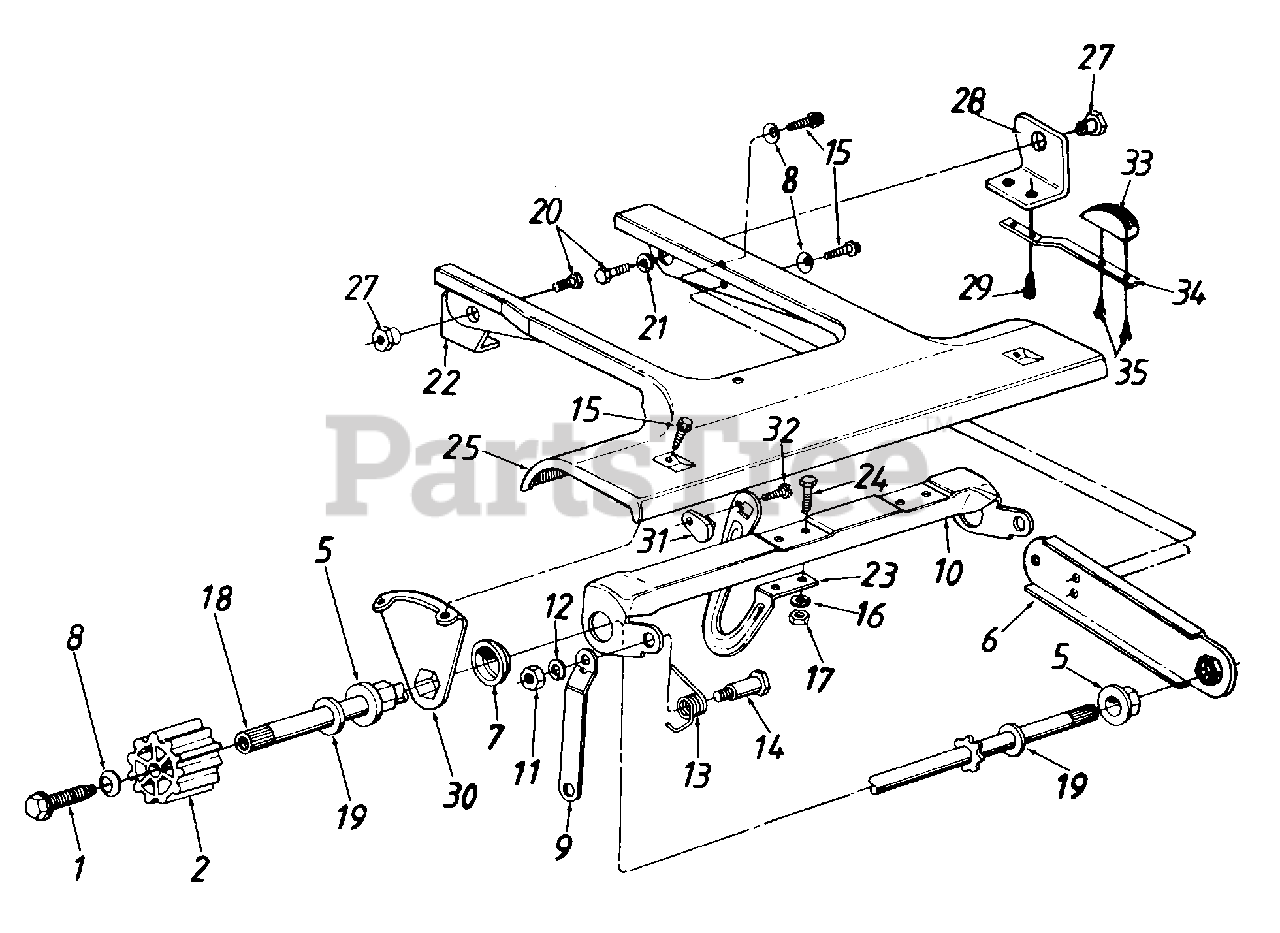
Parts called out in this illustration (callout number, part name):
1	Hex Wash. Hd. Tap Scr. 1/4-20 x .75" Lg.
2	Wheel Drive Pinion
5	Hex Flange Brg. .504" I.D.
8	Bell-Wash. .265" I.D. x .75" O.D.
11	Hex Nut 5/16-18 Thd.
12	L-Wash. 5/16" I.D.
13	Torsion Spring-R.H.
14	Shoulder Bolt .437" Dia.
15	Hex Wash. Hd. AB-Tap Scr. 1/4 x .62" Lg.
16	L-Wash. 1/4" I.D.
17	Hex Nut 1/4-20 Thd.*
18	Drive Shaft Ass'y.
19	Fl-Wash. .531" I.D. x .93" O.D.
20	Hex Bolt 3/8-16 x .5" Lg.*
21	L-Wash. 3/8" I.D.*
32	Hex B-Tap Scr. #10 x .44" Lg.
33	Chain Tensioner
34	Cantilever Spring
35	Hex B-Tap Scr. #10 x .38" Lg.
